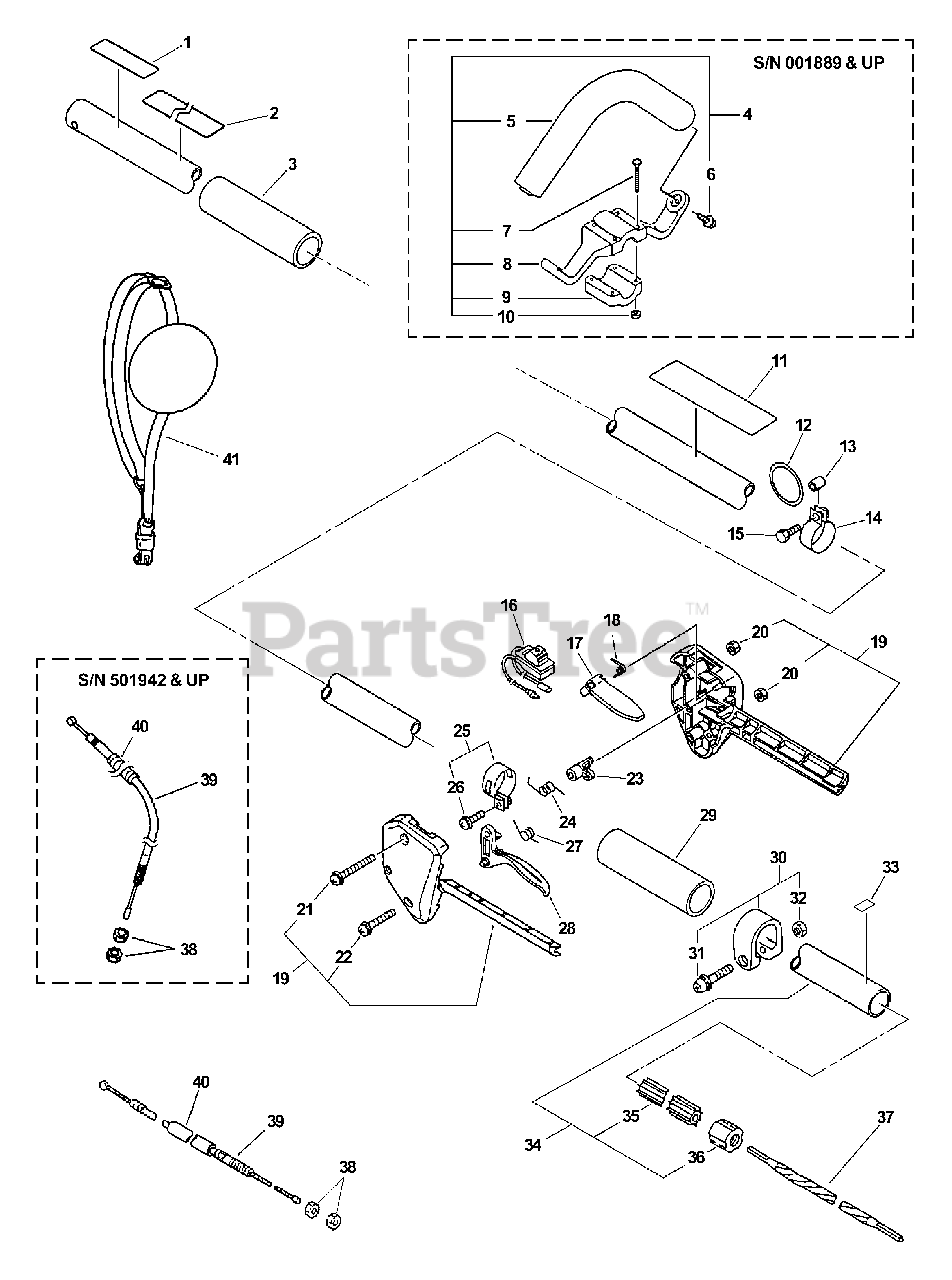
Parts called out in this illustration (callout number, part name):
1	LABEL, CAUTION
2	LABEL - CAUTION
3	GRIP, HANDLE
4	LOOP HANDLE ASSY
5	HANDLE
6	SCREW 5×14
7	SCREW 5×35
8	BRACKET, HANDLE
9	BRACKET, HANDLE - LOWER
10	NUT M5
11	LABEL, CAUTION
12	RING, HARNESS Ø32
13	SPACER, GUARD
15	BOLT 5×18
16	IGNITION SWITCH ASSY
17	LEVER, THROTTLE LOCKOUT
18	SPRING, TORSION
19	THROTTLE BRACKET SET
20	NUT M5
21	SCREW 5×35
22	SCREW 5×25
23	LOCKOUT, TRIGGER
24	SPRING, THROTTLE RETURN
25	CLAMP KIT
26	SCREW 5×14
27	SPRING, TORSION
28	TRIGGER, THROTTLE
29	GRIP, HANDLE
30	CLAMP KIT
31	SCREW 5×28
32	NUT M5
33	LABEL - ALIGNMENT
34	MAIN PIPE ASSY
35	LINER - FLEXIBLE
37	DRIVESHAFT - FLEXIBLE
39	CABLE, THROTTLE
41	SHOULDER STRAP ASSY
